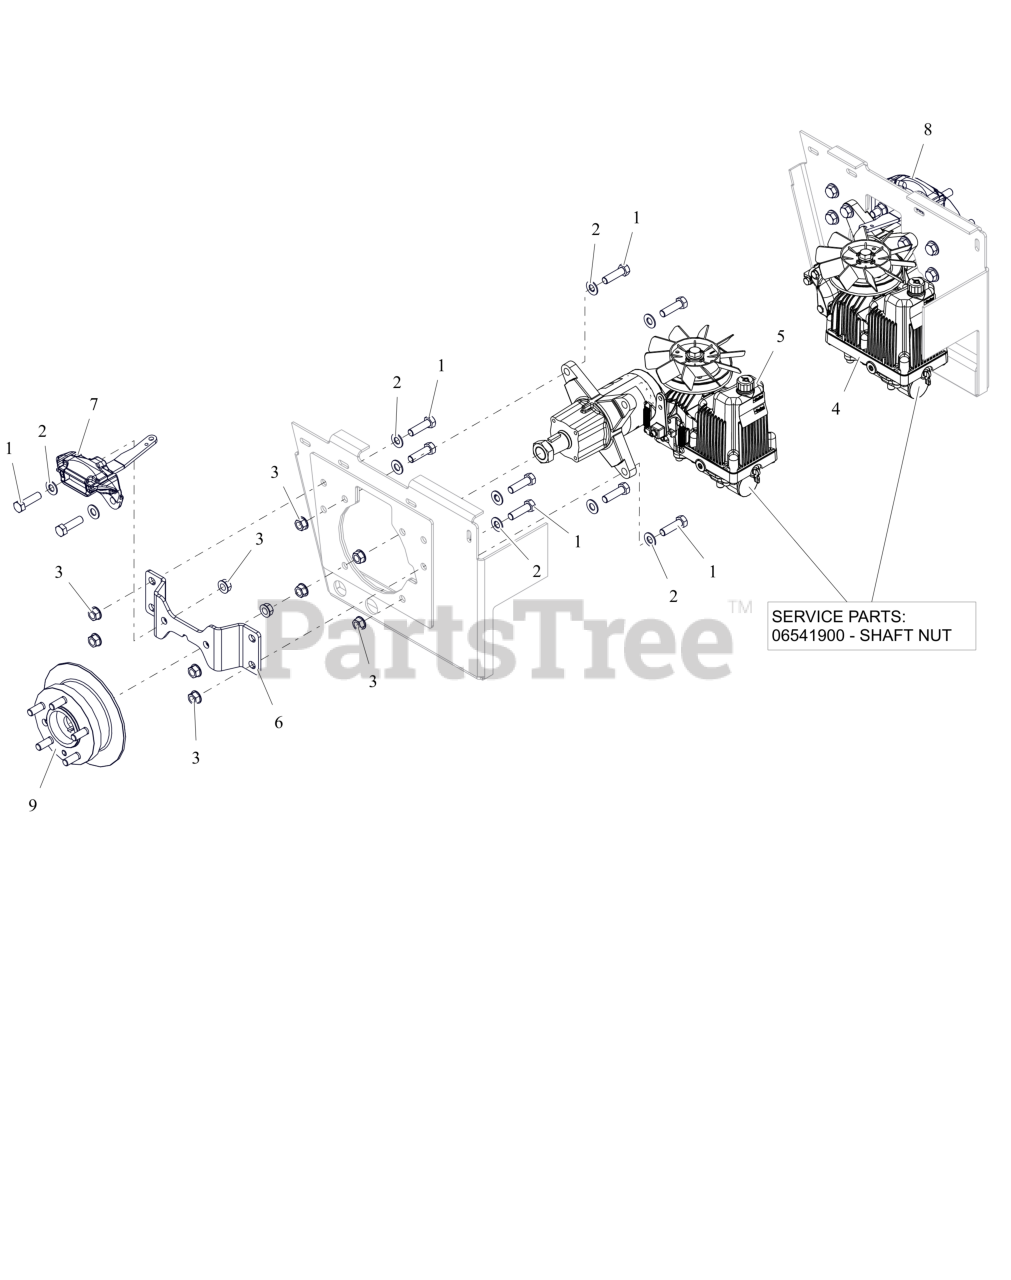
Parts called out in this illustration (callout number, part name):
1	BLT- HEX .50-13 X 1.75 G8 ZCC
2	WSHR, FLT .557X1.040X.102 ZCC
3	NUT, FLG-CTR LK .500-13 GG ZCC
4	TRANSAXLE- LH PARKER HTJ12/260
4	NUT-LK-JAM-PTCH 1.00-20
5	TRANSAXLE- RH PARKER HTJ12/260
5	NUT-LK-JAM-PTCH 1.00-20
6	BRKT, CALIPER MTG (RED)
7	BRAKE, CALIPER RH
8	BRAKE, CALIPER LH
9	ASM- BRAKE ROTOR
